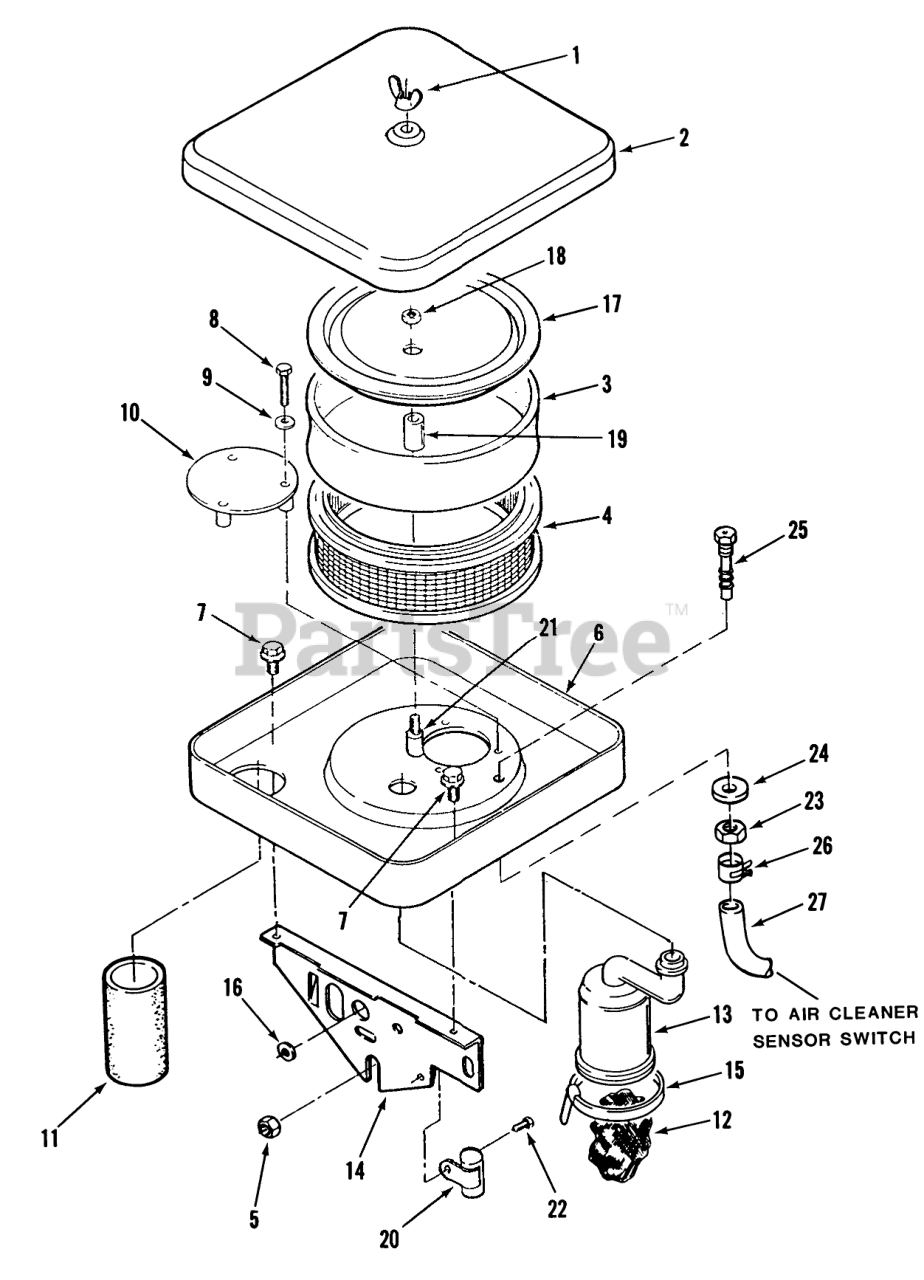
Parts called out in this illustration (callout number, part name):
1	Nut-Wing
2	AIR CLEANER COVER
2	CHROME-AIR CLEANER
2	Air Cleaner Cover
3	AIR CLEANER ELEMENT
3	Air Cleaner Foam Element
4	Air Cleaner Element
5	Nut
6	Air Cleaner Housing
6	AIR CLEANER HOUSING
6	Air Cleaner Housing 520-HC
7	Screw 1/4-20 x 3/8
8	Screw Hex Hd. #10-32 x 1-1/2
9	Flat Washer #10
10	AIR DEFLECTOR PLATE
11	AIR INTAKE TUBE
12	Baffle
13	BREATHER TUBE
14	AIR CLEANER SUPPORT
15	BREATHER TUBE CLAMP
16	Grommet
17	Element Cover
18	Hex Nut 1/4-20
19	Spacer
20	Condenser
21	Air Cleaner Stud 520-HC Only
22	SCREW #10-32 X 5/8
23	TAPPET NUT
24	HOSE FITTING GASKET
25	Fitting-Barbed
26	Clamp
